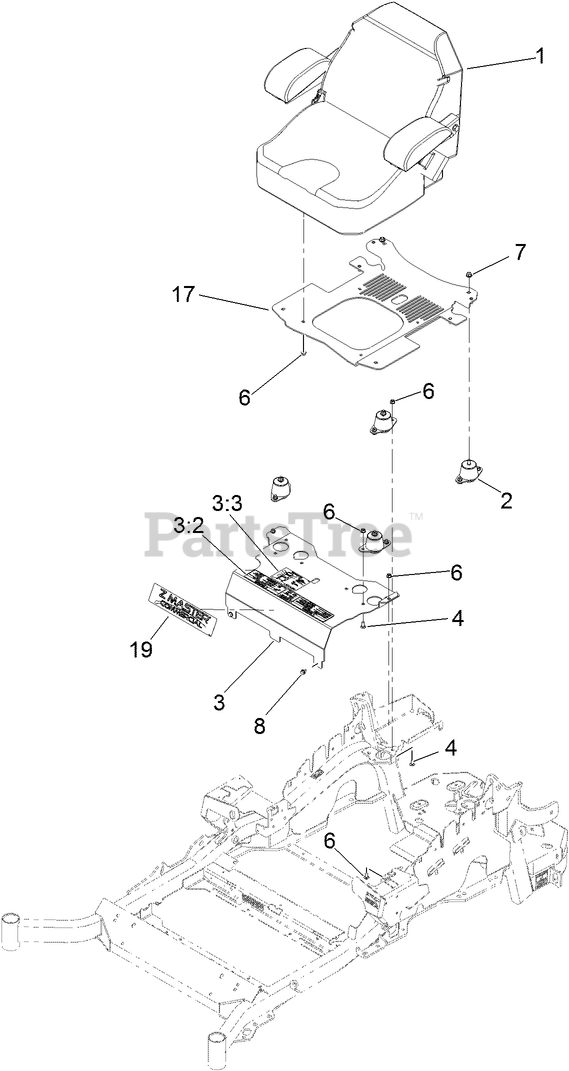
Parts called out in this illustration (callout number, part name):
1	SEAT-STANDARD
2	ISOLATOR-SEAT
3	MOUNT-SEAT
3:2	DECAL-CONSOLE
3:3	DECAL-SERVICE AID
4	SCREW-CARR
6	NUT-HF, NI
7	NUT-HF, NI
8	SCREW
17	SEAT BASE ASM
